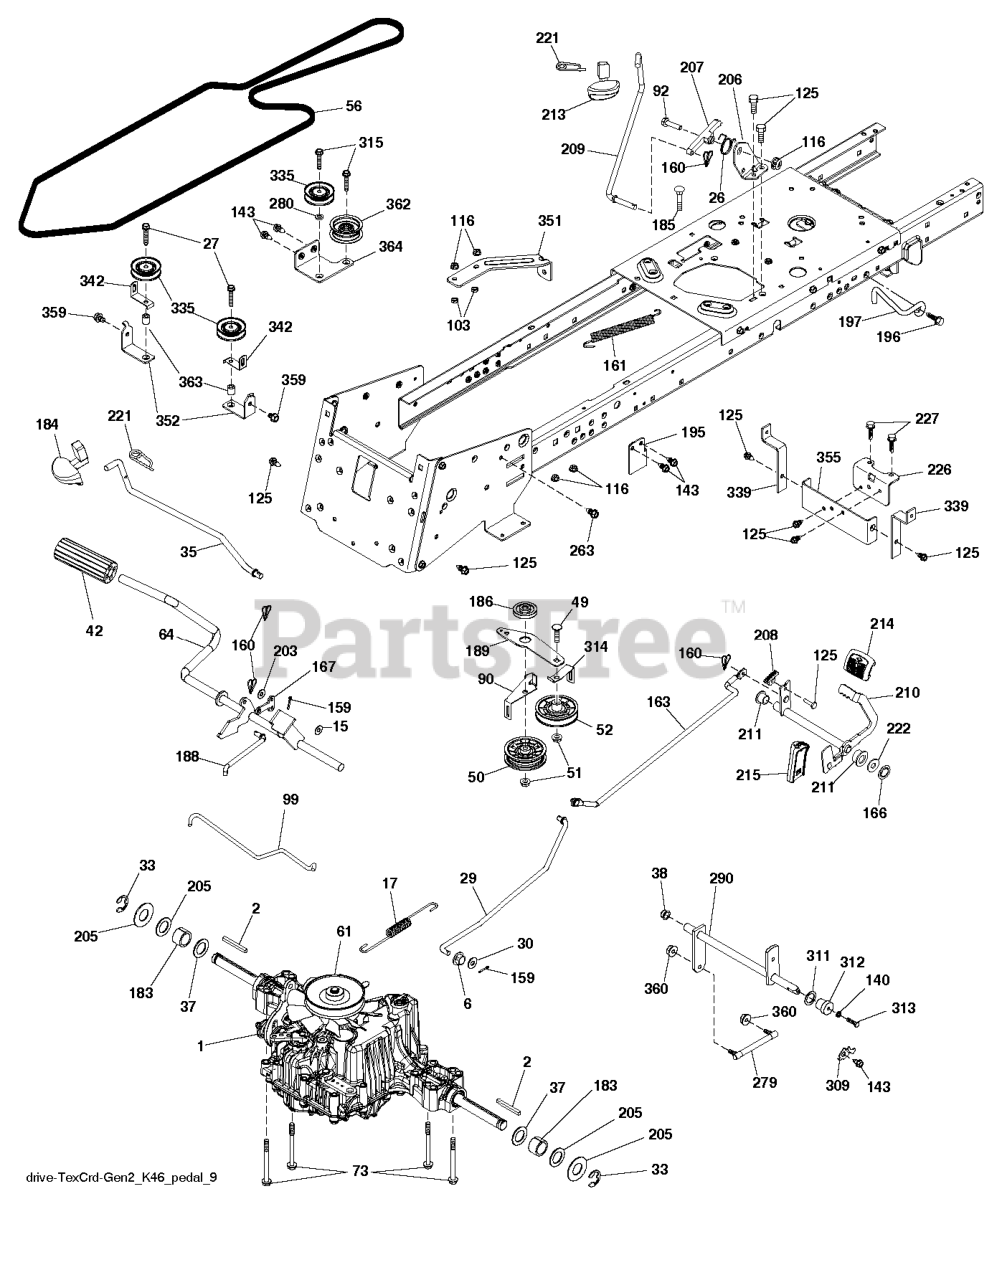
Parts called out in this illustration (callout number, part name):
2	SQUARE KEY
6	BUSHING.SNAP.NYL.BLK.
15	WASHER
17	SPRING
26	SPRING.RETURN.CRUISE
27	SCREW
29	ROD ROD BRAKE K46 TCRD GEN 2
30	WASHER
35	ROD .BRAKE. PARKING. GT. HUSQ.
38	NYLINER SNAP 5/8" ID
42	PEDAL COVER T
50	IDLER.FLAT.910.OFFSET
51	NUT LOCK FLG 3/8-16 UNC
52	IDLER.V-GROOVE.910.OFFSET
56	BELT BELT DRIVE GROUND 114.25
61	PULLEY PULLEY INPUT FLANGED TR
64	SHAFT.ASM.PEDAL.BRK.CNTR
73	BOLT.FLANGED
90	KEEPER KEEPER BELT CLUTCHING T
92	BOLT
99	ROD ROD BYPASS CRD TEX GEN 2
103	JAM NUT TI
116	NUT LOCK HEX FLANGE 5/16-18
125	SCREW
140	LOCKWASHER
143	SCREW LT
159	COTTER PIN
160	RETAINER CLIP
161	SPRING, RETURN LT
163	ROD ROD CONTROL SHIFT PEDAL TC
166	NUT.PUSH.625
167	LATCH.BRAKE.SPRING
183	SPACER AXLE
184	RB HANDLE.PARKG.BRK.HUS/PRED
186	SPACER.RETAINER
188	RP.LINK.CLUTCH.GROUND.DRIVE
189	BELLCRANK BELLCRANK GROUNDDRI
196	SCREW 3/8-16X1
197	LINK.CLUTCH.ANIT-ROTAT
203	WASHER
206	BRACKET.MOUNT.CRUISE.LATCH
207	LATCH.CONTROL.CRUISE
208	GEAR.SECTOR.CONTROL.CR
209	ROD.CONTROL.CRUISE.GT.
210	ROCKER.ASM.PEDAL.CONTR
211	BEARING.NYLON
213	KNOB.CONTROL.CRUSIE.HU
214	PEDAL.FORWARD.PAD.TEX
215	PEDAL RUBBER REVERSE
221	RETAINER.SPRING.CLIP.H
222	WASHER 21/32 X 1-1/4 X 10 GA.
226	BRACKET.MOUNT.TORQUE.K46.TLT
227	SCREW.THDROL.5/16-18X3/4.TTY
263	SCREW, 3/8-16X3/4
279	LINK SUBASM. LINK AND STUD
280	WASHER T
290	SHAFT SUBASM.SHAFT.CROSS.SHIFT
309	PLATE FASTENING LT
311	WASHER NYL
312	HUB.TAPERED.ROUND.CRD
313	BOLT
314	RETAINER KEEPER BELT
315	BOLT.5/16-18X1.25
335	PULLEY.V-IDLER.
339	STRAP STRAP TORQUE K46 CRD TE
342	BELT GUIDE
351	BRACKET BRACKET DECK SWAY
352	BRACKET BRACKET IDLER CRD TEX
355	STRAP STRAP TORQUE K46 CRD TEX
359	SCREW LT.3/8-46X5/8
360	NUT NUT HEX CENTERLOCK 5/16-24
362	IDLER.FLAT.2.25.INCH
363	SPACER SPACER 343X63X.62
364	BRACKET BRACKET IDLER CRD TEX
